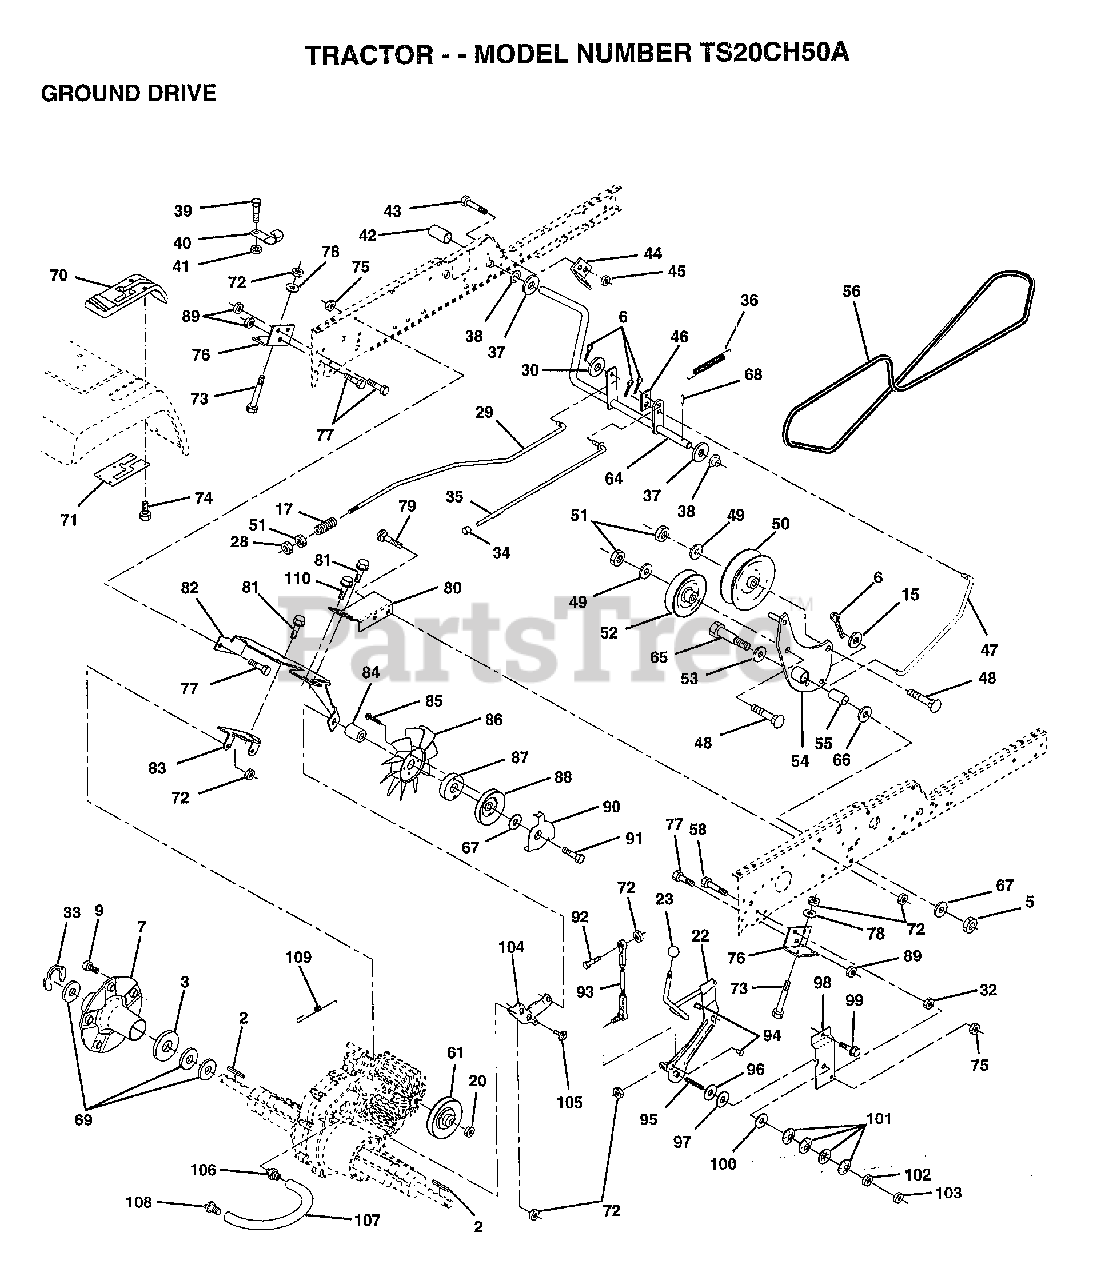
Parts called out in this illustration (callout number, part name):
2	KEY 1/4 X 2.5
3	WASHER T
6	COTTER PIN
7	HUB WHEEL ASM
9	BOLT.HUB.WHL.REAR
15	WASHER
17	SPRING ROD BRAKE
22	SHAFT ARM ASM
23	KNOB.DUCKHEAD.1/2
28	NUT
29	ROD BRAKE
30	WASHER HYT
32	NUT
33	E RING HYT
34	PLUNGER CAP T
35	ROD BRAKE PART GT
36	SPRING.GRND.DRIVE
37	WASHER
38	NYLINER T
39	SCREW
40	ACT-SWITCH T
42	PEDAL COVER T
43	BOLT LT
44	BRKT SWITCH GT
45	NUT
46	RETAINER.SPRING
47	ROD.CLUTCH
48	BOLT
49	WASHER
50	FLAT IDLER PULLEY
51	NUT
52	PULLEY.IDLER.V.GR
53	WASHER T
54	ARM.ASM.IDLER.CLU
55	"LY, BEARING"
56	BELT-V 84.5
58	BOLT
61	PULLEY TRANSAXLE
62	NUT
65	AXLE BOLT
66	WASHER.HARD.BLADE
67	WASHER
68	ROLL PIN STD
69	WASHER
71	PLATE CONSOLE S
73	BOLT FIN HEX 5/16
74	SCREW HEXWSH H-L
75	NUT.7/16
76	BRACKET TRAN VGTH
77	BOLT
78	WASHER
79	BOLT
80	BRACKET TORQUE RH
81	SCREW
83	STRAP TORQUE MID
84	SPACER
85	SCREW YTV
86	"FAN 7"" HYDRO"
87	ADAPTER FAN
89	NUT GTV
90	KEEPER BELT
91	SCREW.HXWSH.3/8
93	LINK ASM SHIFT
94	XMAS TREE FASTNER
95	SCREW SET 5/16
96	WASHER NICKEL PLT
97	BEARING THRUST
98	BRACKET SHIFT
99	SCREW LT
100	WASHER COMPRESSIN
101	WASHER
102	NUT HEX NYLOCK
103	JAM NUT TI
104	BRACKET IDLER
105	SCREW CRT
109	SPRING BRAKE
110	HINGE SCREW
